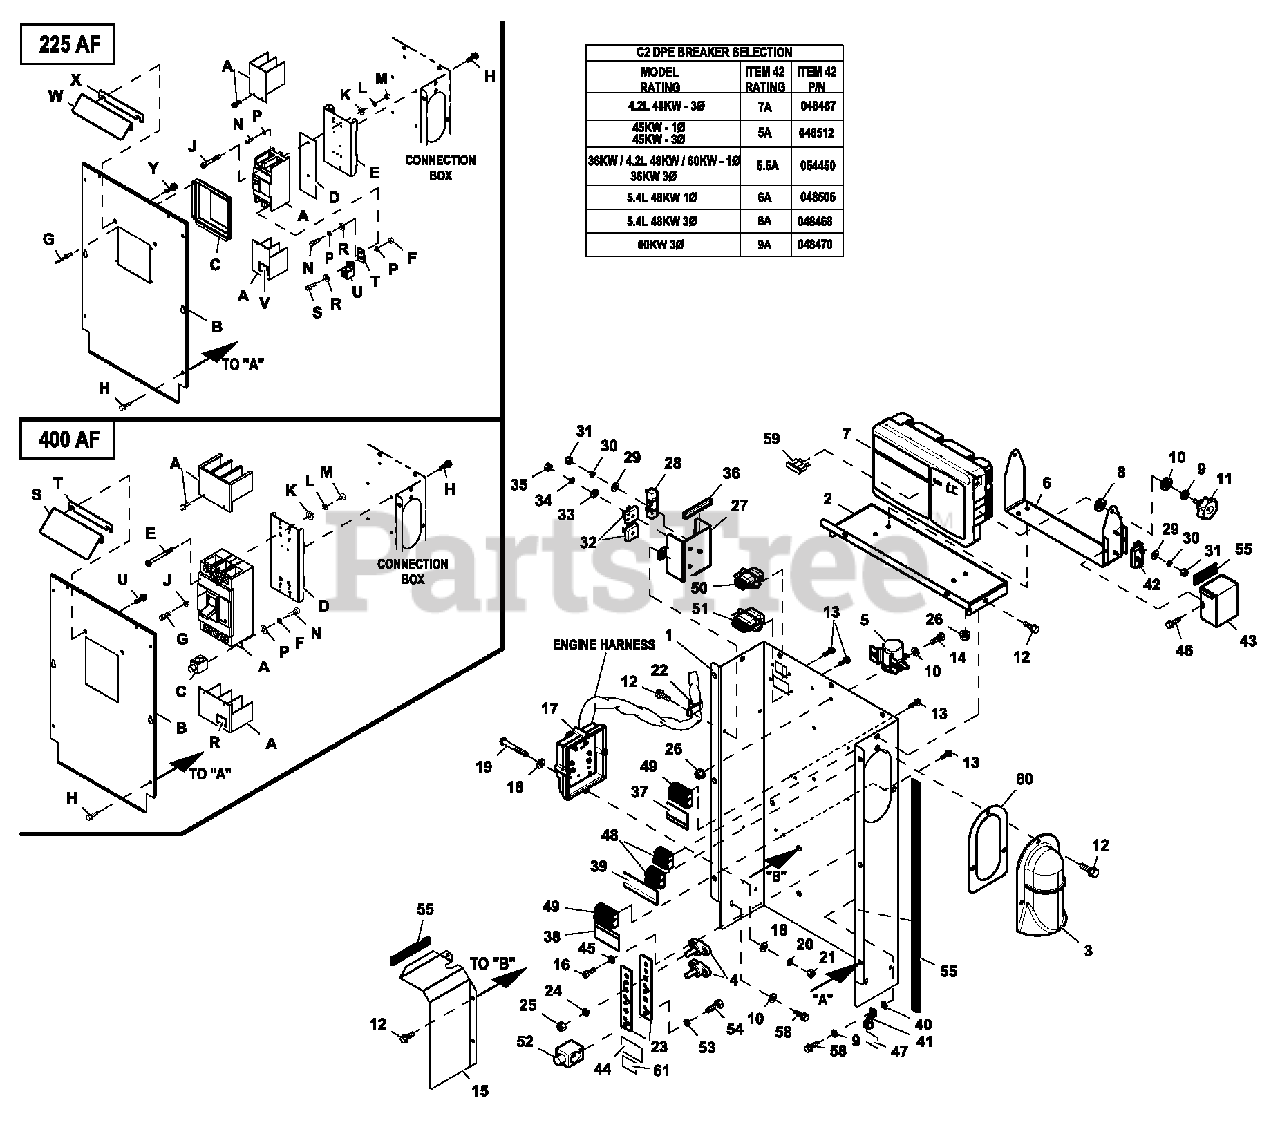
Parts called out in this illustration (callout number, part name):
1	BACK PANEL CONBOX SUPPORT C2
2	TOP PANEL CONBOX SUPPORT C2
3	COVER WIRE ENTRY CONBOX
4	JUNCTION BLOCK 3/8-16
5	RELAY SOLENOID 12VDC PNL MNT
6	BRACKET GIMBAL CONTROL PNL RAW
7	ASSY CTRL PROGRAMMED
8	WASHER FLAT NYLON 0.257 X 0.625
9	WASHER LOCK M6-1/4
10	WASHER FLAT 1/4-M6 ZINC
11	KNOB M6-1.0 CONTROL PANEL
12	SCREW HWHT M6-1 X 16 N WA Z/JS
13	SCREW HHSP #10 X 3/8 HI-LOW
14	SCREW HHC M6- 1.0 X 20 C8.8
15	SHIELD HIGH/LOW C2 RAW
16	SCREW PHTT M4-0.7 X 12 ZP
17	ASSY PROG 2010 IGN MOD 6 CYL
18	WASHER FLAT #10 ZINC
19	SCREW PPHM # 1 0 -3 2 X 2
20	WASHER LOCK #10
21	NUT HEX #10-32 STEEL
22	CLAMP STL/VNL 1.06 X .406 Z
23	NEUTRALoBLOCKo390/200 4 0 0A o
24	WASHER LOCK 3/8
25	NUT HEX 3/8-16 STEEL
26	NUT FLANGE M6-1.0 NYLOK
27	COVER VOLTAGE SHIELD
28	RES W W 15R 5% 25W QK CONN
29	WASHER FLAT M3
30	WASHER LOCK M3
31	NUT HEX M3-0.5 G8 CLEAR ZINC
32	DIODE BRIDGE 1P 35A 1000V
33	WASHER FLAT M5
34	WASHER LOCK M5
35	NUT HEX M5-0.8 G8 CLEAR ZINC
36	TRIM VINYL BLACK 1/8GP (3" LG)
37	DECAL CUSTOMER POWER CONNECT
38	DECALoCUSTOMERoCONTROLoCONNECTo
39	DECAL CONBOX TB1 CONNECTIONS
40	WASHER LOCK EXT 1/4 STL
41	LUG SLDLSS #2-#8 X 17/64 CU
42	CIRCUIT BREAKER
43	COVER DPE BREAKER NEXUS RAW
44	DECAL NEUTRAL
45	WASHER LO C K#8-M4
46	SCREW HHTT M4-0.7 X 8 ZP
47	DECAL GROUND LUG
48	TERM BLOCK 3P UL 12-20AWG
49	TERM BLOCK 4P UL 12-20AWG
50	MX15 0 L SLRRMNT 22-18 8P W/O GA
51	MX150L SLRRMNT 22- 18 12P W/OGA
52	LUG SLDLSS 600/250-1/0X1/4-28
53	WASHER LOCK 1/4- M6 SS
54	SCREW HHC 1/4-28 X 3/4 G5
55	TAPE ELEC 1/2 FOAM (69" LG)
57	HARNoCONBOXoNEXUSo(NOToSHOWN)o
58	SCREW HHTT M6-1.0 X 16 ZYC
59	FUSE ATO TYPE 7.5AMP (BROWN)
60	GASKEToWIREoENTRYoCOVERo
61	DECAL CAUTION ELEC SHOCK SM
A	CB 175A 2 POLE 240V 225AF
B	COVER CB C2 CPL
C	COVER CB DISH 2P G 225AF
D	INSULATOR CB 2P 225AF
E	STANDOFF CB BOX CONBOX
F	NUT HEX M8-1.25 G8 CLEAR ZINC
G	RIVET POP .125 X .275 SS
H	SCREW HWHT M6-1 X 16 N WA Z/JS
J	SCREW RHM # 8 -3 2 X 3 -1 /4
K	WASHER FLAT #8 ZINC
L	WASHER LO C K#8-M4
M	NUT HEX #8-32 STEEL
N	SCREW SHC M8-1.25 X 20 G8
P	WASHER LOCK M8-5/16
R	WASHER FLAT 5/16-M8 ZINC
S	SCREW SHC M8-1.25 X 25 C12.9
T	BUS BAR 200A LUG ADAPTOR
U	LUG SLDLSS 300 MCM-6 AL/CU
V	DECAL TERMINAL SHOCK HZD BI
W	SHIELD-SM CIRCUIT BREAKER
X	GASKET-CB SHIELD C2
Y	SCREW HWHTF M6-1.0 X 1 6
A	CB 0250A 3P 480V G 400AF
B	COVER CB 400AF C2 CONBOX
C	LUG SLDLSS 600/250-1/0X1/4-28
D	STANDOFF CB MOUNT CONBOX
E	SCREW RHM 1 0 -3 2 X 4
F	WASHER LOCK M6-1/4
G	SCREW SHC M10-1.5 X 25 C12.9
J	WASHER LO C KM 10
K	WASHER FLAT #10 ZINC
L	WASHER LOCK #10
M	NUT HEX #10-32 STEEL
N	SCREW HHC 1/4-28 X 1/2 G5
P	WASHER FLAT 1/4-M6 ZINC
R	DECAL TERMINAL SHOCK HZD BI
S	SHIELD-LGE CIRCUIT BREAKER
T	GASKET-CB SHIELD C2
U	SCREW HWHTF M6-1.0 X 1 6
